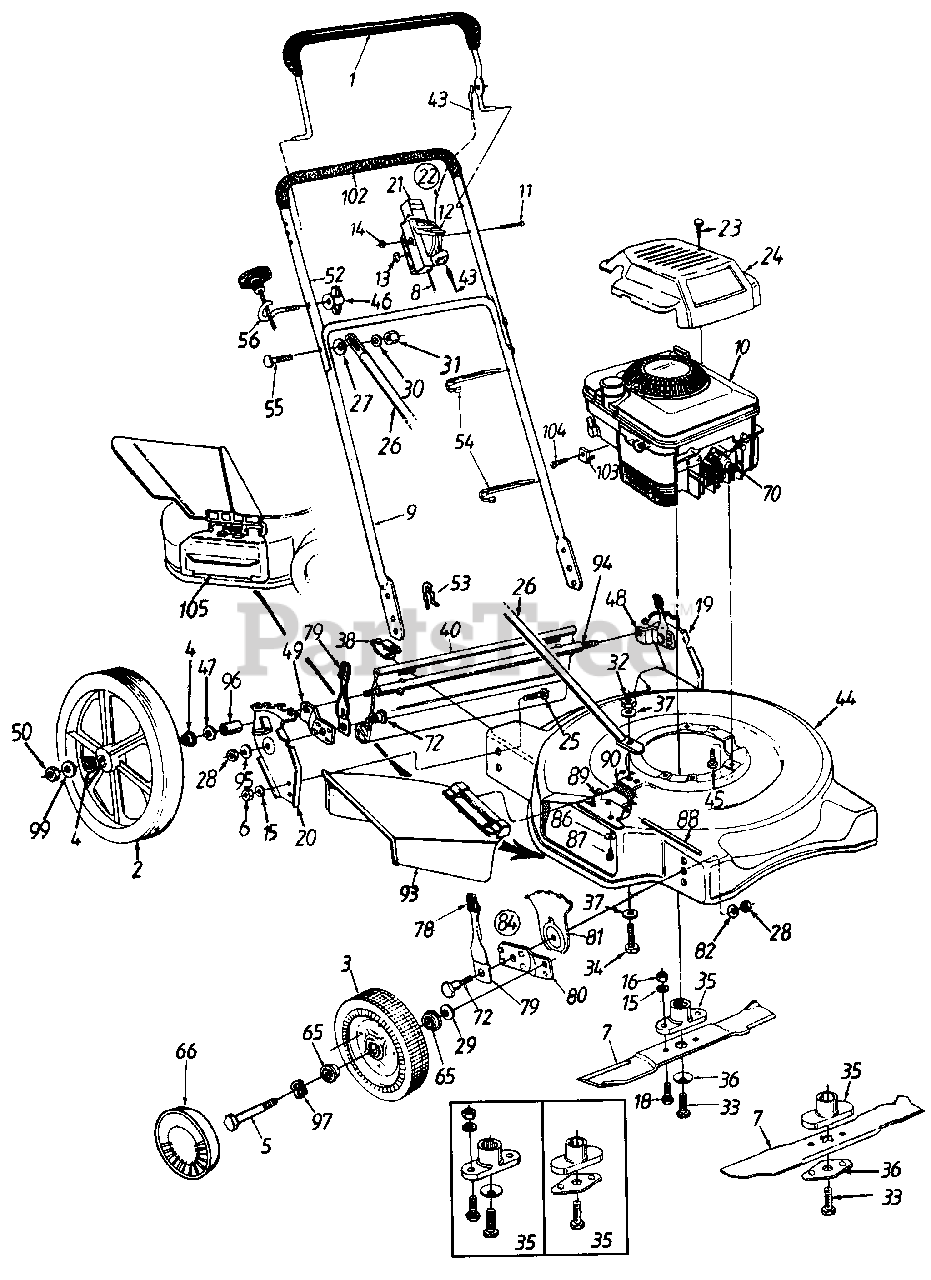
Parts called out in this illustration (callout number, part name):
1	Control Handle
2	16" Wheel Ass'y.
3	Front Wheel Ass'y.
4	Bearing 1/2" I.D.
5	Front Axle Bolt
6	Hex Nut 3/8-24 Thd. (Gr. 8)
7	22" Blade
8	Throttle Control Wire - 51"
10	Engine
11	Oval C-Sunk Mach. Scr.
12	Throttle Lever
13	Spr. Wash. .66" I.D.
14	Hex L-Nut 1/4-20 Thd.
15	L-Wash. 3/8" I.D.
16	Hex Nut 3/8-24 Thd.
18	Hex Bolt 3/8-24 x 1.0" Lg.
19	Handle Brkt. Ass'y. - L.H.
20	Handle Brkt. Ass'y. - R.H.
21	Throttle Body
22	Throttle Box Comp.
23	Hi-Lo Scr. #10 x 1.25" Lg.
24	Engine Shroud
25	Ribbed Neck Bolt 3/8-24 x .80"
27	Saddle Wash. .32" I.D.
28	Hex Nut 3/8-16 Thd.
29	Bell-Wash. .400" I.D. x .88"
30	L-Wash. 5/16" I.D.
31	Hex Nut 5/16-18 Thd.
32	Hex Nut 1/4-20 Thd.
33	Hex Bolt 3/8-24 x 1.5" Lg.
34	Hex Bolt 1/4-20 x 5/8" Lg.
35	Blade Adapter Kit
36	Blade Bell Support
37	Bell-Wash. 1/4" I.D.
38	Hinge Clip
40	Rear Flap Ass'y.
43	Control Cable - 39"
44	22" Deck Ass'y.
45	Hex Wash. Hd. TT-Tap Scr. 3/8-16 x 1.00" Lg.
46	Handle Knob 1/4-20 Thd.
47	Wave Wash. .51" I.D.
48	Small Pivot Bar - L.H.
49	Small Pivot Bar - R.H.
50	Hex Jam Nut 3/8-16 Thd.
54	Cable Tie
55	Curved Hd. Bolt 5/16-18 x 2" Lg.
65	Bearing
66	Hubcap
70	Spark Plug Boot
72	Shoulder Bolt .50" Dia.
78	Hgt. Adj. Knob
79	Spring Lever Ass'y. w/Knob
81	Height Adj. Plate
82	Bell-Wash. .39" I.D. x 1.38"
84	Front Height Adj. Ass'y. Comp. - R.H.
86	Bell-Wash. .285" I.D. x .75"
87	Hex Wash. Hd. Tap Scr. 1/4-20 x .5" Lg.
88	Hinge Pin
89	Adapter Plate
90	Torsion Spring
93	Chute Deflector Ass'y. Comp.
95	Bell-Wash. .39" I.D. x 1.13"
96	Spacer .55" I.D. x .75"
97	Wave Washer .51" I.D.
99	Fl-Wash. .406" I.D. x .81"
103	Casing Clamp
104	Hex Wash. Hd. Tap Scr. #10-32 x .62" Lg.
105	Mulching Baffle
